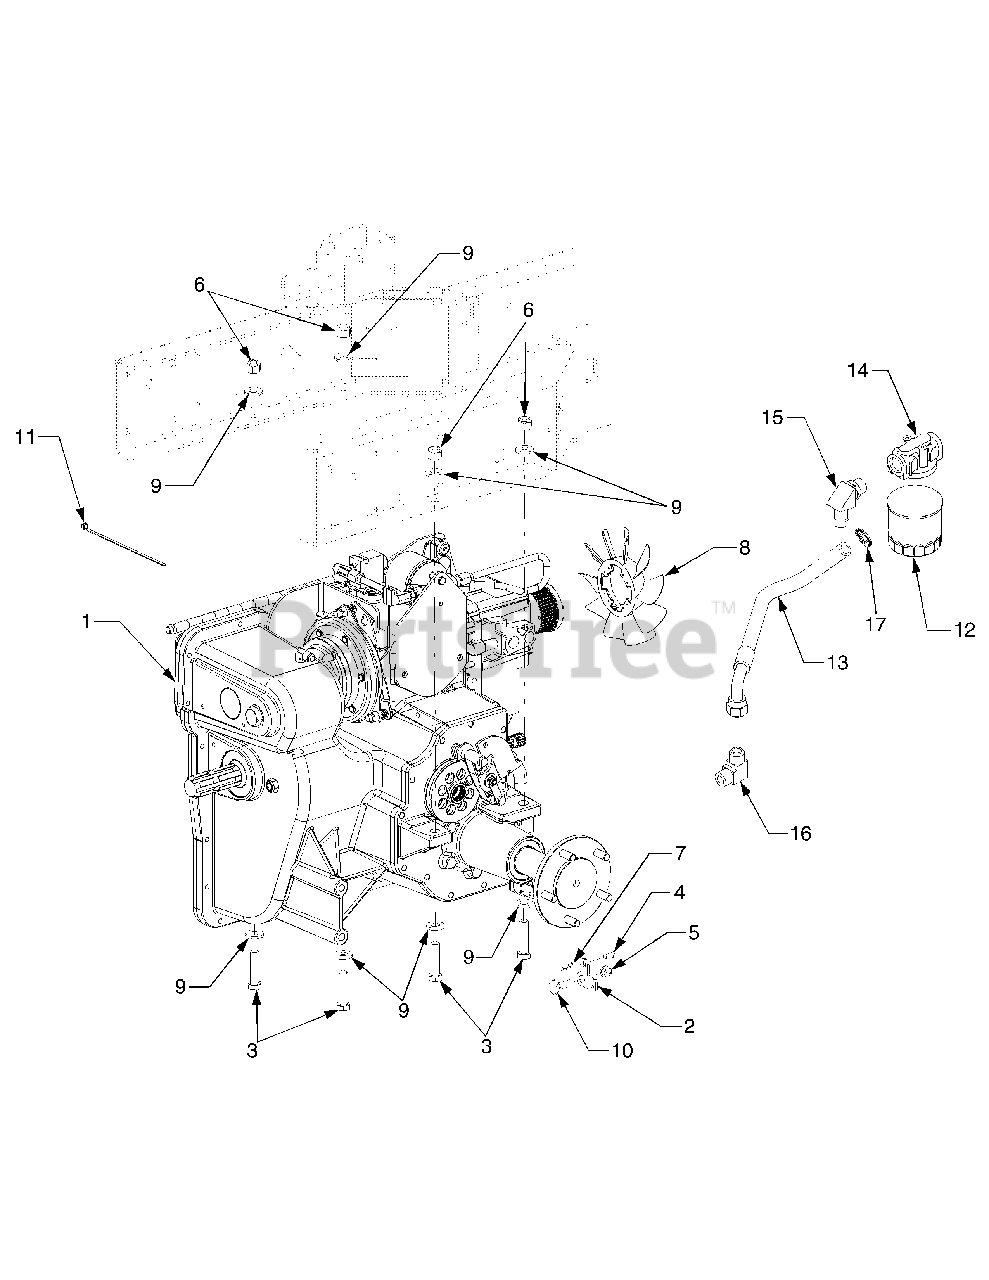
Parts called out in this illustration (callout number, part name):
1	Transmission Assembly
2	Link, Diff Lock Actuator
3	Screw, Hex Cap 1/2-13 x 2.0 GR8
4	Pin, Clevis, .25 x .50
5	Nut. Hex Insert Lock, 3/8-24
6	Nut, Hex Insert Lock, 1/2-13
7	Pin, Internal Cotter
8	Fan, Transmission Cooling
9	Washer, Flat, .531 x .1062 x .134 .
10	Screw, Shoulder, 1/2 Dia. x .180 ..
11	Tie, Cable
12	Filter, Oil
13	Hose, Filter
14	Adapter, Oil Filter
15	Fitting, 45° Elbow
16	Fitting, 90° Elbow
17	Clamp, Adjustable Hose
